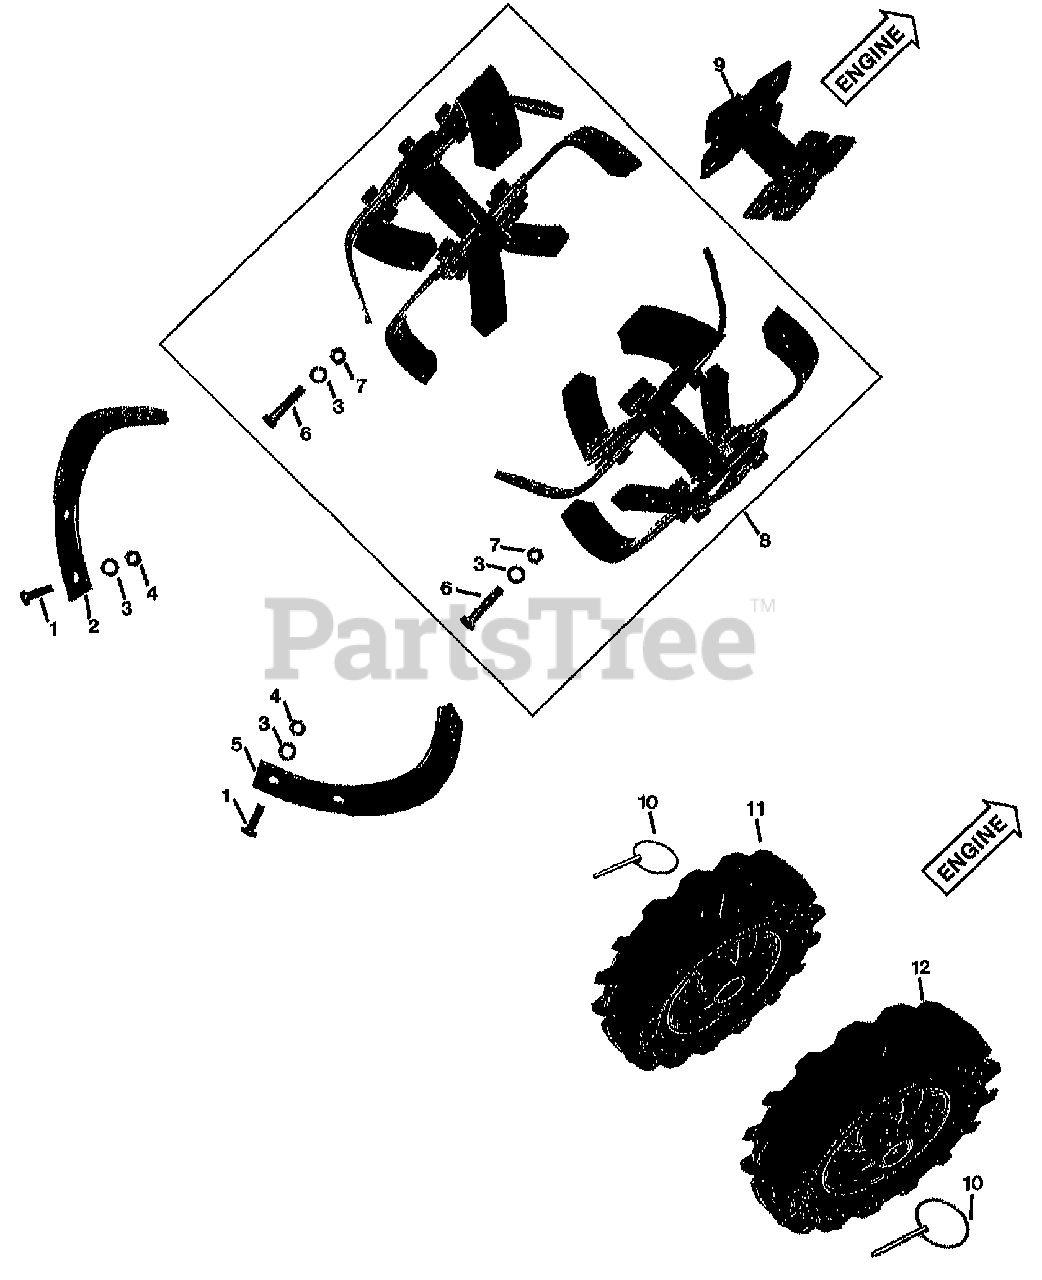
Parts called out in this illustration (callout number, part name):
1	SCR-HH 3/8-16X1.0 G5 ZP (Tine mounting)
2	TINE-BOLO LEFT SINGLE
3	WASHER-LK .375 @ DEPL (SEE ILLUSTRATION)
4	NUT-HEX 3/8-16 ZP
5	TINE-BOLO RIGHT
6	BOLT-HH 3/8-16X1.75 G8 ZP (Tine holder to tiller shaft)
7	NUT-H/LK 3/8-16
8	KIT-TINE & HOLDER 16 Tines, assembled.
9	TINE HOLDER-WELD (FOR Bolo Tines, LT and RT sides)
10	PIN-QUICK RELEASE (Wheel hub to shaft)
11	ASSM-TIRE&WHL LH GRAY
12	ASSM-TIRE&WHL RH GRAY
